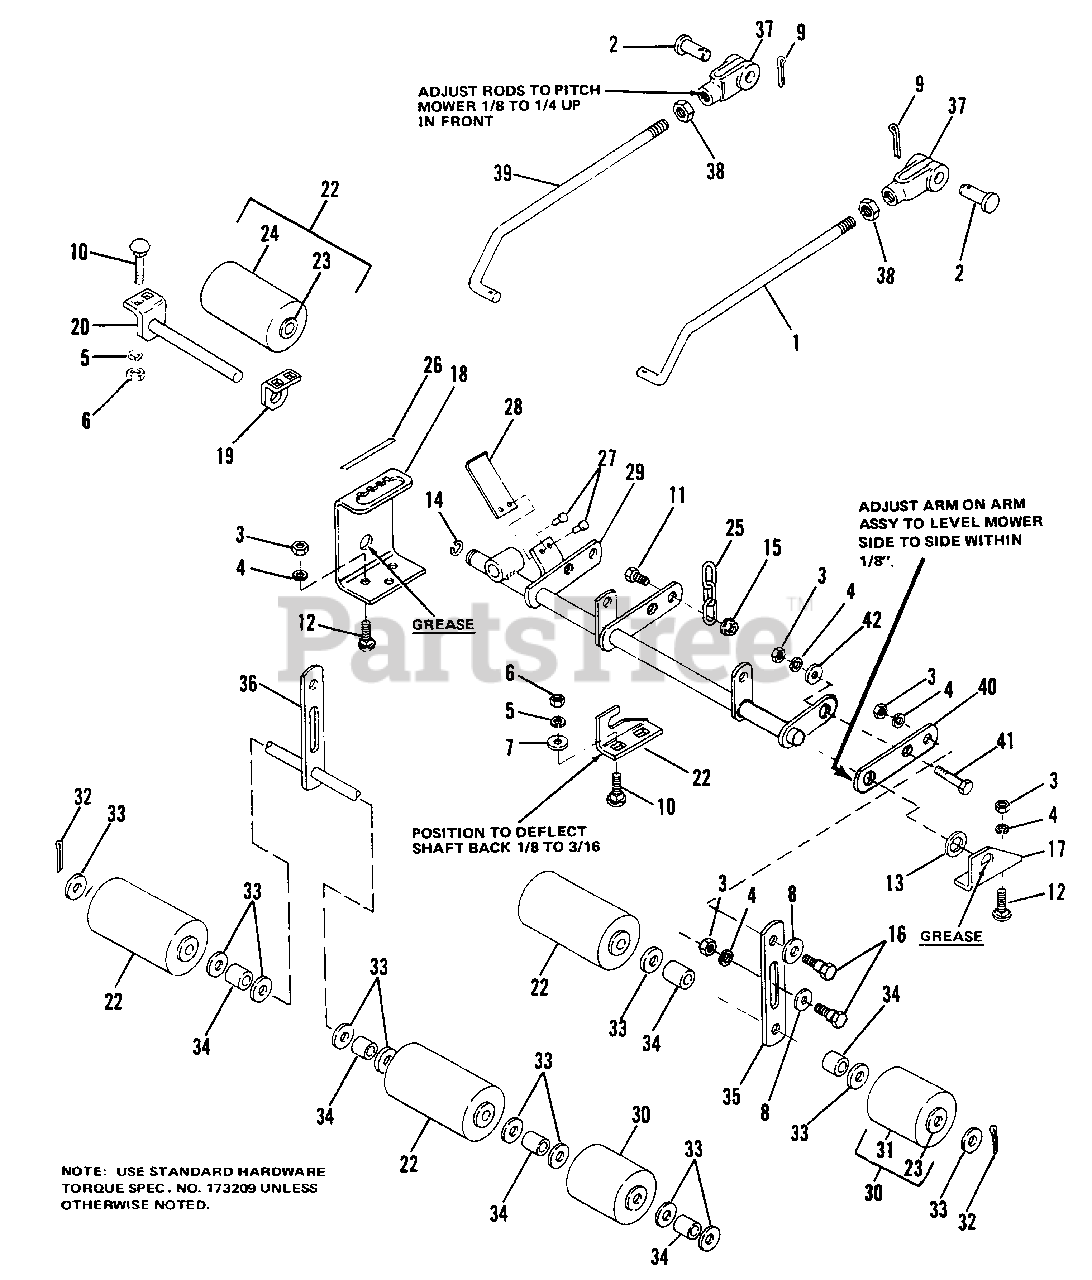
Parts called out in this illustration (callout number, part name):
1	ROD, L.H., Mower Adjusting
2	PIN, Yoke
3	NUT, Hex, 3/8-16
4	LOCKWASHER, Spring, 3/8
5	LOCKWASHER, Spring, 5/16
6	NUT, Hex, 5/16-18
7	WASHER, Plain, 5/16
8	WASHER, Plain, 7/16
9	PIN Cotter, 1/8 x 1
10	BOLT, Carriage, 5/16-18 x 3/4
11	CAPSCREW, Hex Hd., 3/8-16
12	BOLT, Carriage, 3/8-16 x 3/4
13	WASHER, Plain, 3/4
14	RING, Retaining No. 75, 3/4
15	NUT, Flange, 3/4-16
16	BOLT, Shoulder, 3/8-16 X 1.34
17	BRACKET, Pivot, L.H.
18	QUADRANT, Mower Control
19	BRACKET, Center Support
20	SHAFT ASSY, Center Roller
21	BRACKET, Lift
22	ROLLER ASSY
24	ROLLER, Mower
25	CHAIN, Lift
26	DECAL, Mower Height
27	RIVET, Pop
28	SPRING, Mower Quad.
29	ARM ASSY, Mower
30	ROLLER SUB-ASSY
31	ROLLER
32	PIN, Cotter, 3/16 x 1
33	WASHER, Plain, 5/8
34	SPACER, .66 ID
35	BAR, Roller
36	SHAFT ASSY, Roller
37	YOKE, End Adj.
38	NUT, Hex Jam, 1/2-20
39	ROD, R.H. Mower Adjusting
40	ARM, Mower
41	CAPSCREW, 3/8-16 x 1-1/4
